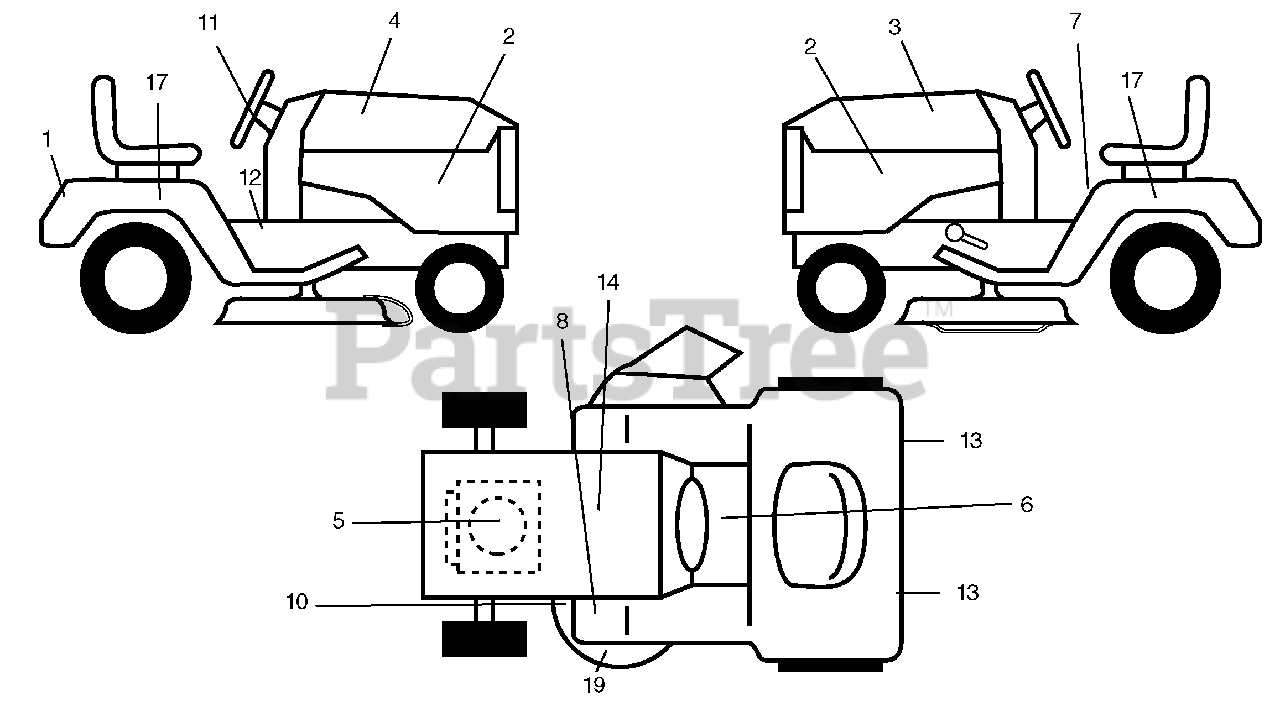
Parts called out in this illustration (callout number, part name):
1	Decal Fender
2	Decal Side Panel
3	Decal Hood LH
4	Decal Hood RH
5	Decal HP Engine
6	Decal Parking Brake
7	Decal Danger Fender English
8	Decal Clutch/brake English
10	Decal V-Belt Sch
11	Decal Steering
12	Decal Oper sDL Eng
13	Reflector Taillight
14	Decal, Btry Dngr/Psn
17	Decal Fender Side
19	Decal Cntrl Movement
19	Pad, Footrest
19	Decal Handle Lft Height Adjust
19	Manual, Owner's (English)
